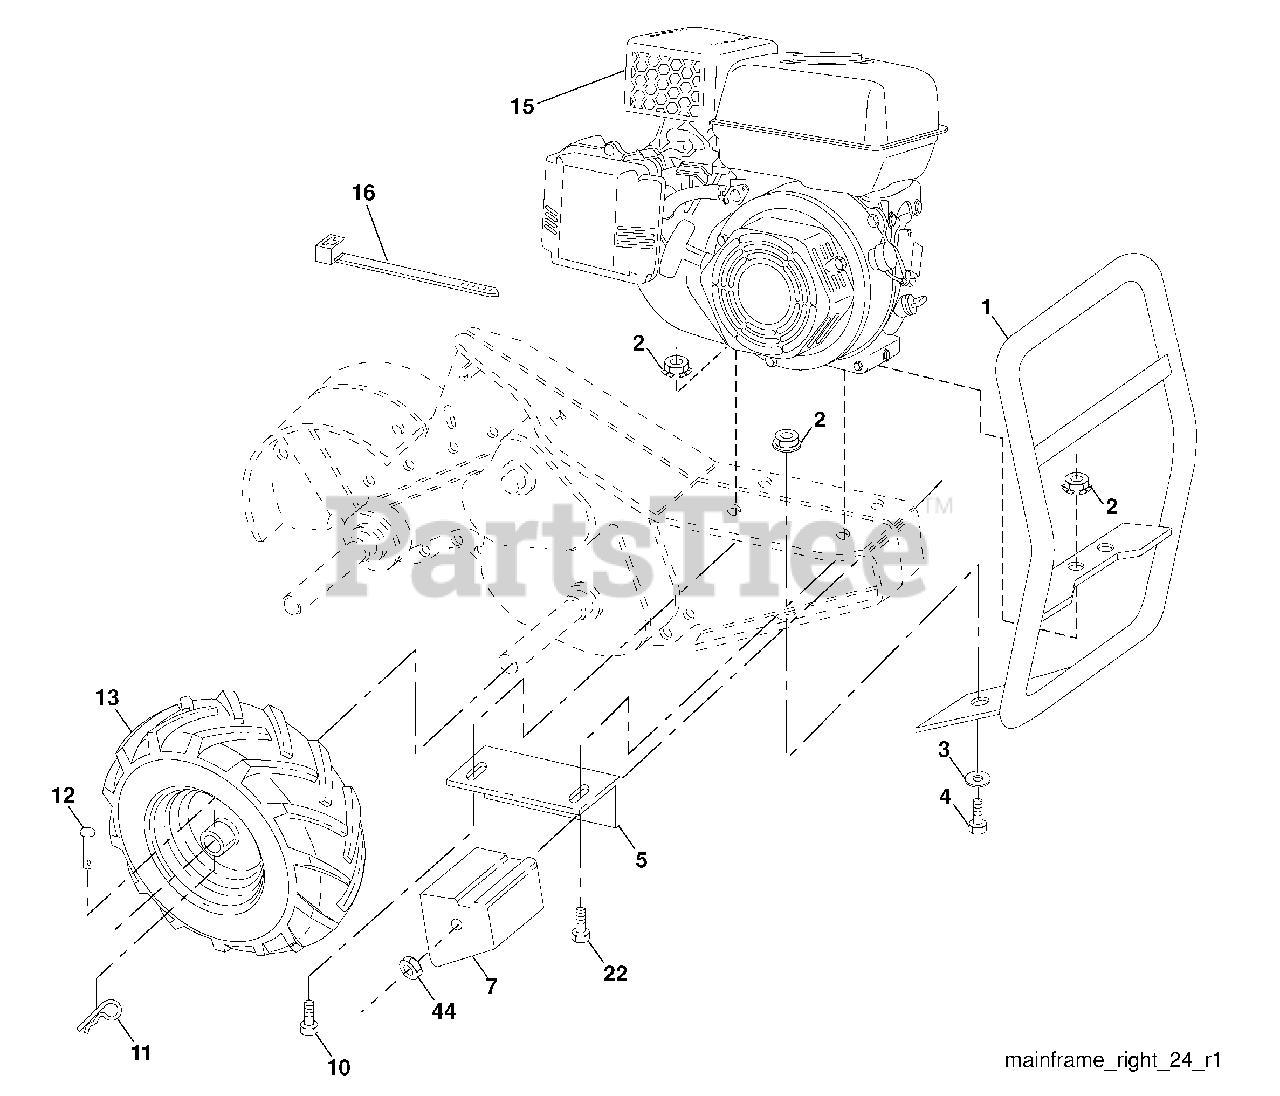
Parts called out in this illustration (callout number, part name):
2	Locknut, Hex, Flange 5/16-18
3	Washer 11/32 x 11/16 x 16 Ga.
4	Bolt, Hex 5/16-18 x 3/4
5	Bracket, Reinforcement
7	Counter Weight, R.H.
10	Bolt, Hex 5/16-18 x 1-1/2
11	Clip, Hairpin
12	Rivet, Drilled
13	Tire
13	Rim
13	Tire Valve
22	Bolt, Hex 5/16-18 x 1-3/4
44	Nut, Keps, Hex 3/8-16 unc
